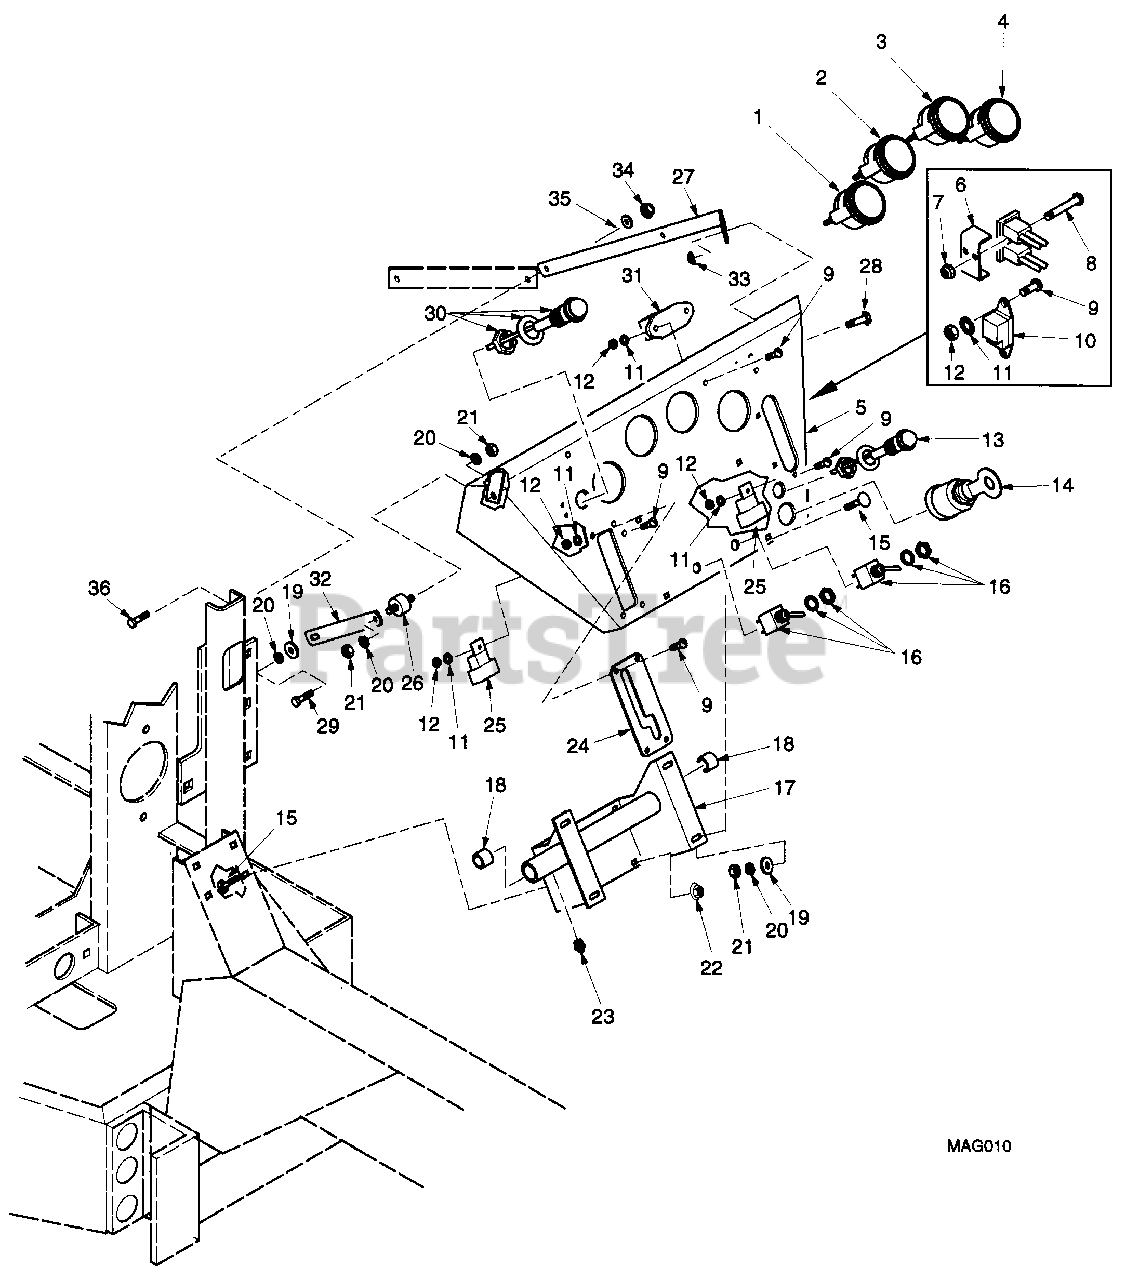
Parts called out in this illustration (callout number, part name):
1	HOURMETER
2	GAUGE, WATER TEMPERATURE
3	GAUGE, FUEL LEVEL
4	VOLTMETER
5	INSTRUMENT PANEL WITH DECAL
6	BRACKET, FUSE HOLDER
7	HEX LOCKNUT, ELASTIC STOP, #10-32
8	SCREW, ROUND HEAD, #10-32 X 1-1/2
9	SCREW, ROUND HEAD, #10-32 X 1/2
10	TIMER, GLOW PLUG
11	LOCKWASHER, EXTERNAL TOOTH, #10
12	HEX NUT, #10-32
13	INDICATOR LIGHT, GLOW PLUG
14	KEYSWITCH
15	CARRIAGE BOLT, 5/16-18 X 3/4
16	SWITCH, DECK LIFT
17	MOUNTING BRACKET, INSTR PANEL(INC 18, 23)
18	BUSHING, OILITE - .75 I.D.
19	FLATWASHER, 5/16(.281 X .625 X .065)
20	LOCKWASHER, 5/16
21	HEX NUT, 5/16-18
22	SERR. FL. HEX NUT, 5/16-18
23	GREASE FITTING
24	GUIDE, CLUTCH LEVER
25	RELAY, SYNCHRONIZE START AND CUTTER BLADE
26	RUBBER ISOLATOR
27	BRACE, INSTRUMENT PANEL
28	SERR. FLG. HEX HEAD CAPSCREW, 5/16-18 X 3/4
29	BOLT, HEX HEAD, 5/16-18 X 3/4
30	INDICATOR LIGHT, OIL PRESSURE
31	TIMER, DELAY CIRCUIT
32	BRACKET, SUPPORT BRACE
33	SERR. FL. HEX NUT, 5/16-18
34	HEX NUT, ELASTIC STOP, 3/8-16
35	FLATWASHER, 3/8(.391 X .938 X .105)
36	BOLT, HEX HEAD, 3/8-16 X 1-1/4
